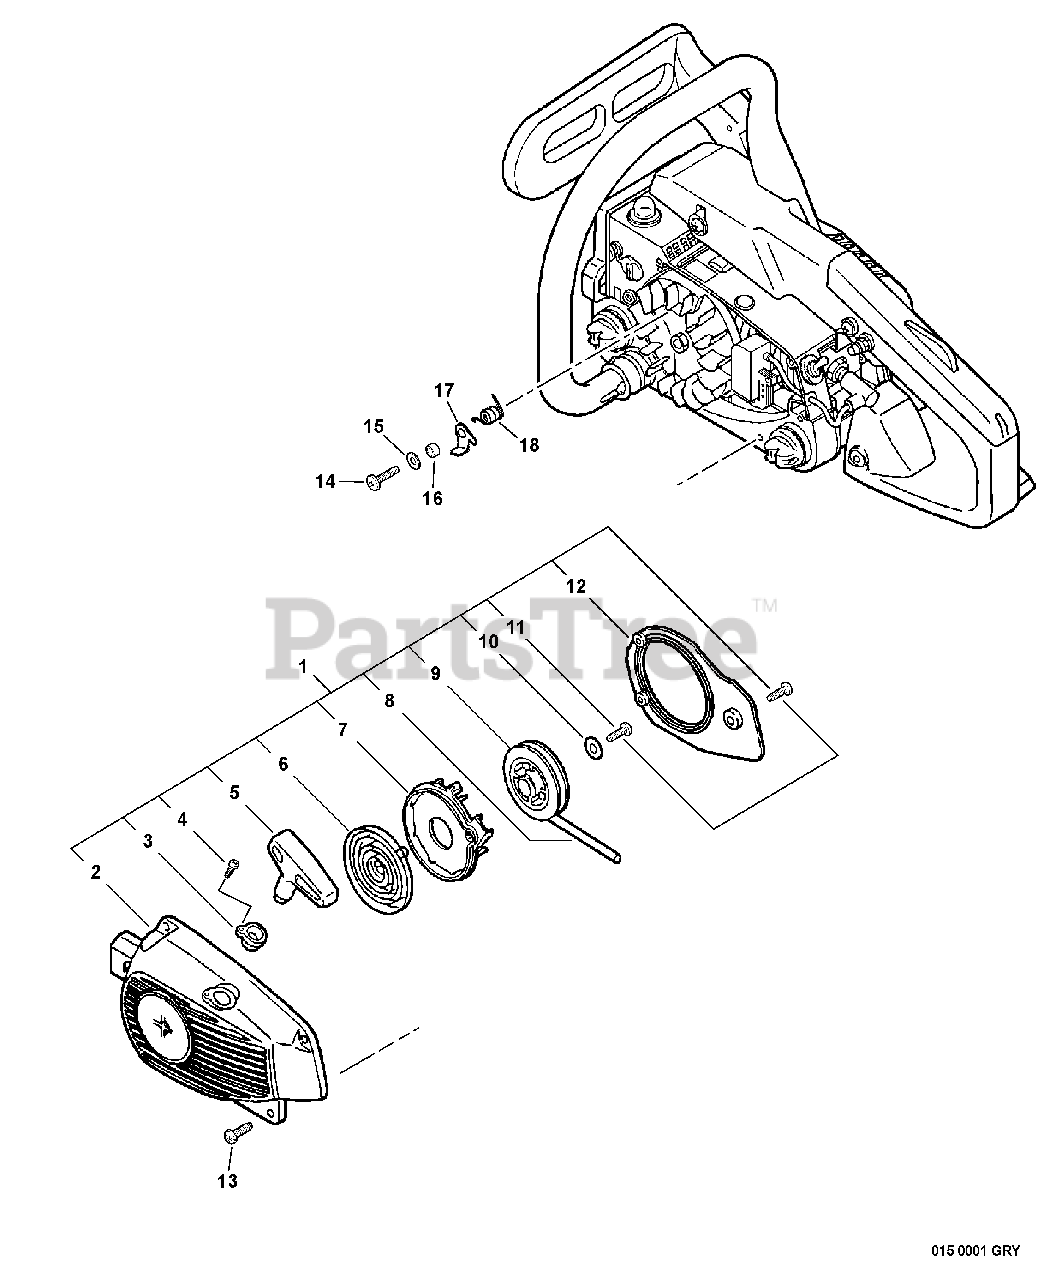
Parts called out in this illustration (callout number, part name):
1	STARTER ASSY
2	CASE, STARTER - GRAY
3	GUIDE, ROPE
4	SCREW - 3X14
5	GRIP, STARTER
6	REWIND SPRING ASSY
7	PLATE, STARTER
8	ROPE, STARTER - 3X850
9	REEL, ROPE
11	SCREW - 4X14
13	SCREW - 4X16
14	SCREW - 5X12
15	WASHER - 5
17	PAWL, STARTER
18	SPRING, RETURN
